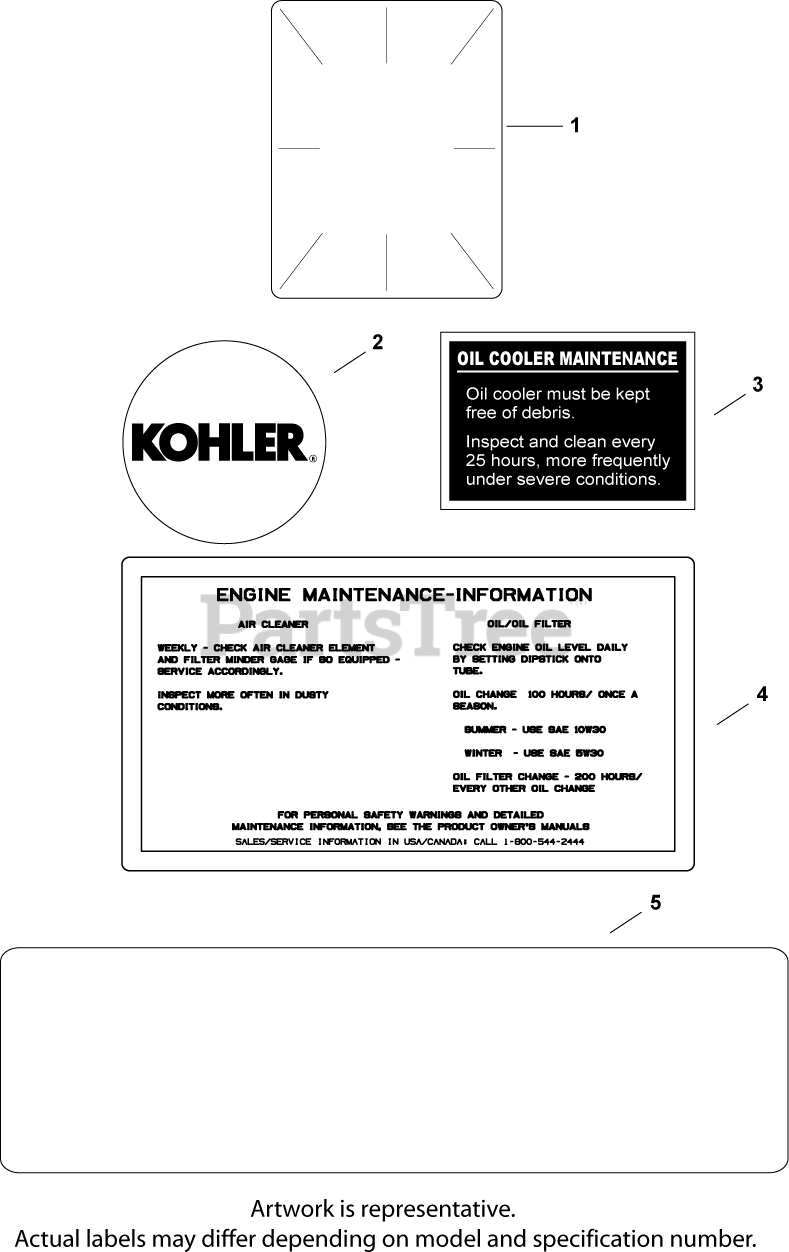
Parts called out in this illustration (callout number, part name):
1	DECAL, CLEAR LAMINATE USE 25 113 70-S
2	LABEL, (ROUND KOHLER GOLD)-USE 24 113 18
3	DECAL, OIL COOLER - (#DSC)
4	DECAL, AIR CLEANER - (#DSC)
5	DECAL, 27 HP
